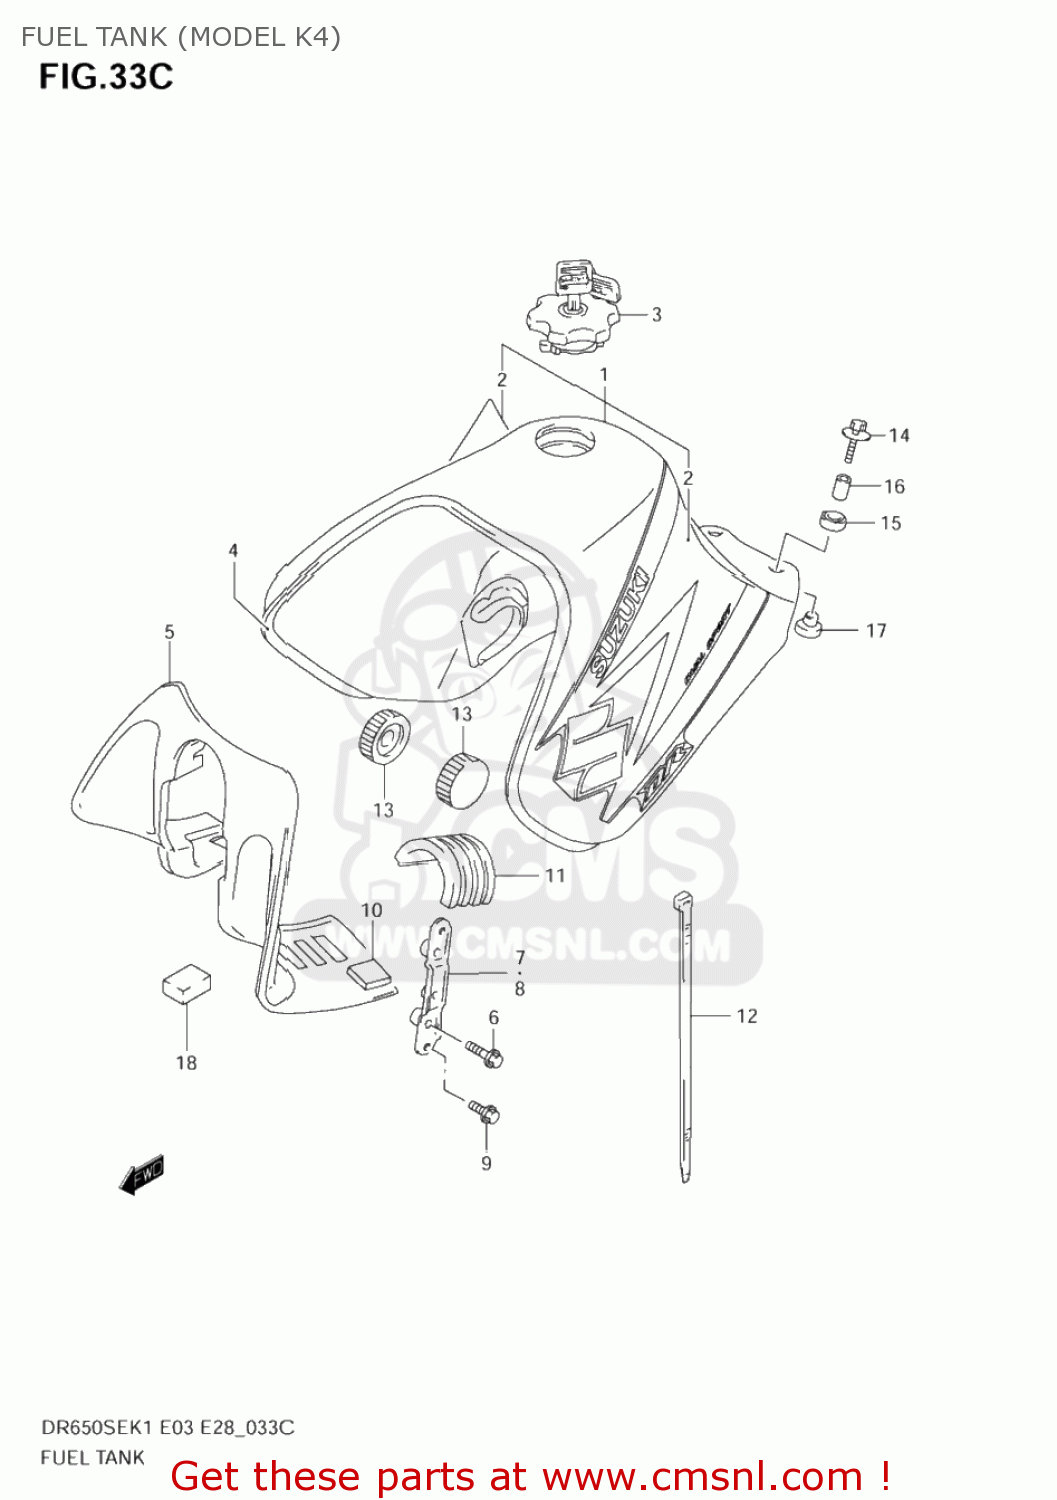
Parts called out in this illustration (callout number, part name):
1	TANK ASSY,FUEL(BLUE)
2	TAPE SET,FUEL TANK
3	CAP SET,FUEL TANK
4	MOLDING,FUEL TANK
5	COVER,FUEL TANK FR
6	BOLT 6X14
7	BRACKET,FUEL TANK COVER,R
8	BRACKET,FUEL TANK COVER,L
9	BOLT
10	CUSHION,HEADLAMP COVER
11	CUSHION,FUEL TANK UPR
12	CLAMP(L:250)
13	CUSHION,FUEL TANK FR
14	BOLT(6X30)
15	CUSHION
16	SPACER(6.5X9X18)
17	CUSHION
18	CUSHION
